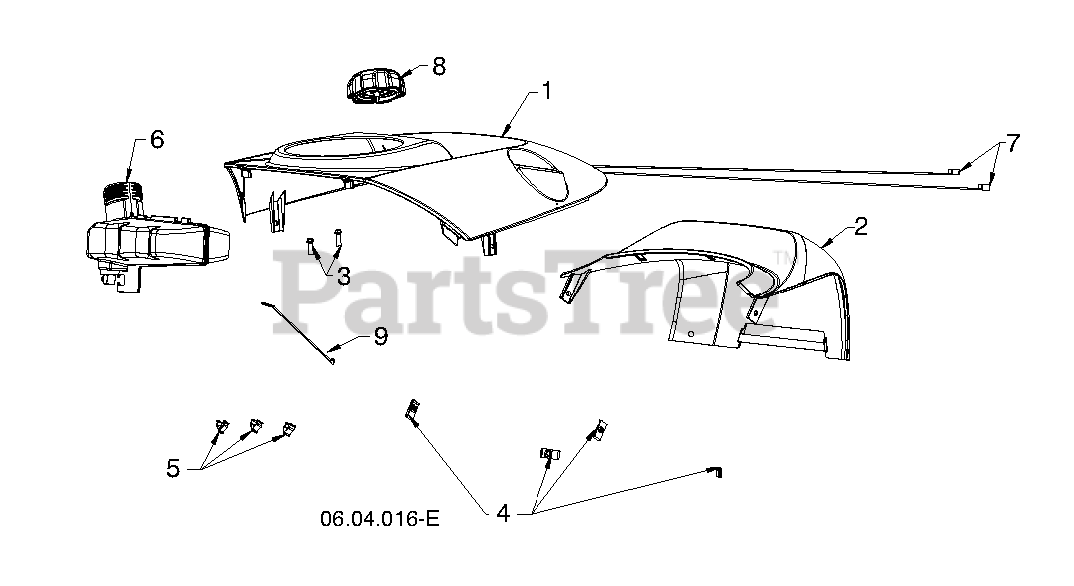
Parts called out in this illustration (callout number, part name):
1	COVER TOP.COVER
2	COVER TOP.REAR.COVER
3	SCREW.HX.13X.750
6	RP_TANK.GAS.12.SINGLE.STAGE.SN
7	TIE.CABLE.24.5X.29.NYLON.WHITE
8	CAP.2.25'.VENTED.RATCHET.EPA
9	WIRE.TIE
